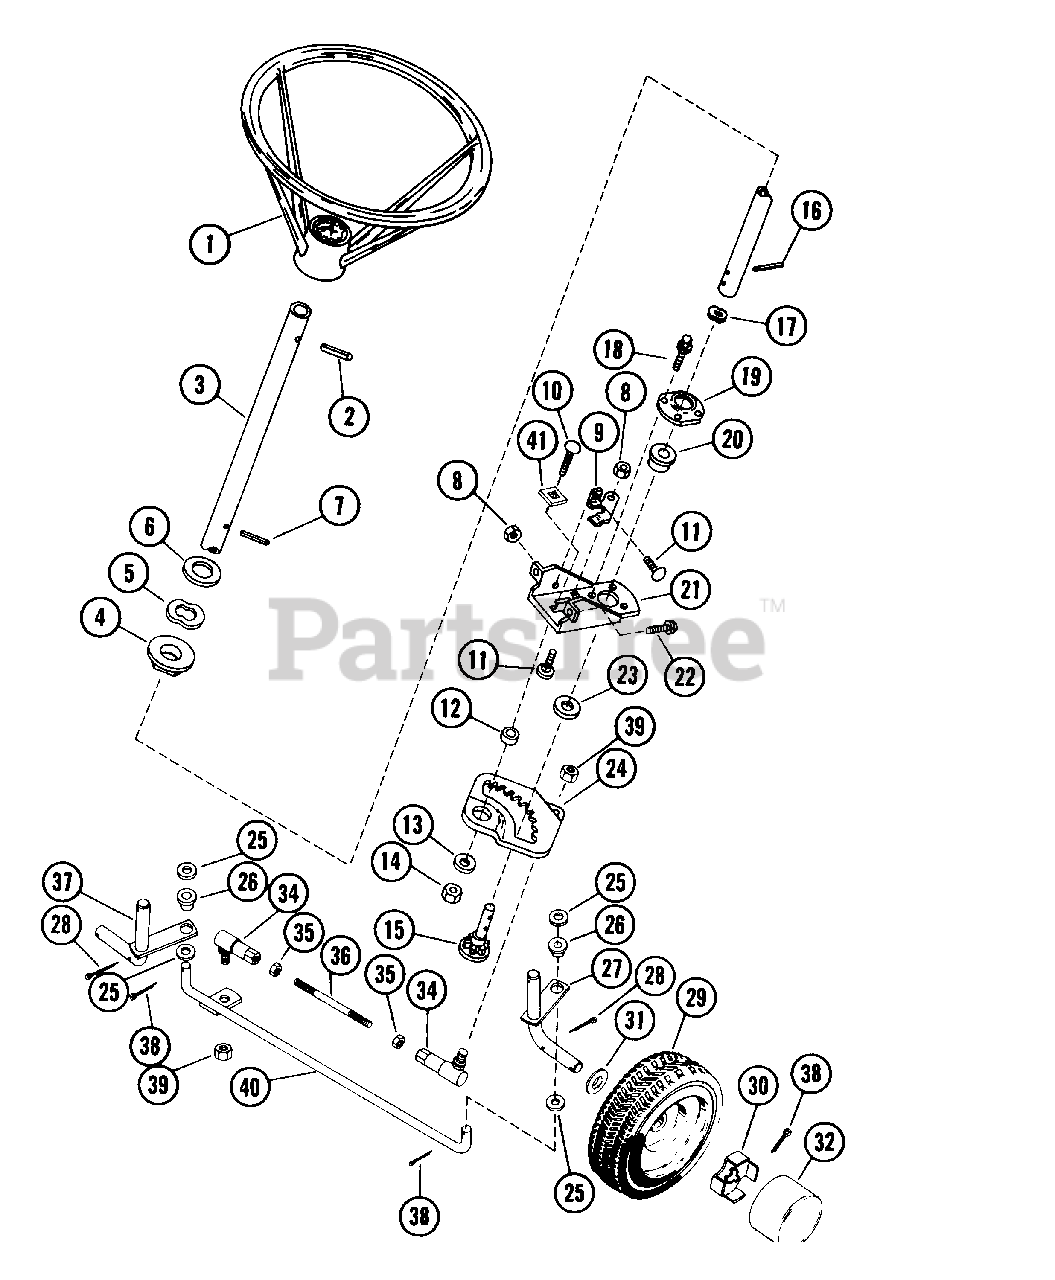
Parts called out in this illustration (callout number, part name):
1	STEERING WHEEL
2	PIN-ROLL .250X1.75
3	STEERING SHAFT
4	FLANGE BUSHING
5	SPRING WASHER
6	WSHR-FL-STL .755X1.375X.062 PL
7	PIN-ROLL .188X1.25
8	NUT-LK-CTR .250-20 PL
9	ADJUSTMENT BRACKET
10	BLT-RDHDSQSHNK .38-16X1.00 PL
11	BLT-RDHDSQNK .25-20X.62 PL
12	SPACER .380X.750X.236
13	WSHR-FL-STL .390X1.500X.125
14	NUT-LK-CTR .375-16 GR A PL
15	STEERING PINION
16	PIN-ROLL .188X1.00
17	WAVE WASHER .531X.781X.125FH
18	SCR-TAP 10-24X.25 CRSLPH PL 1A
19	RETAINING PLATE
20	BSHG-FLG .625X1.156X.375 SI
21	STEERING BRACKET
22	BLT-SERHFWH .31-18X.50 PL
23	WSHR-FL-STL .630X1.005X.062 PL
24	STEERING GEAR
25	WSHR-FL-STL .505X.875X.024 PL
26	BSHG-FLG.500X.625X.312X.750NY
27	L H WHEEL SPINDLE
28	PIN-COTR .12 X 1.25 PL
29	FRONT WHEEL ASSEMBLY
29	TIRE 4.10/3.50-4
29	WHL
29	ZERK FITTING
29	BSHG-FLG .750X1.380X.750X1.557
29	BRG-BALL .752X1.50X.50
30	SPINDLE CUP
31	SPINDLE WASHER
32	HUB CAP
34	BALL JOINT
35	NUT .375-24 PL
36	STEERING LINK
37	R H WHEEL SPINDLE
38	PIN-COTR .12X1.0 PL
39	NUT-LK .375-24 PL
40	TIE ROD
41	WASHER
